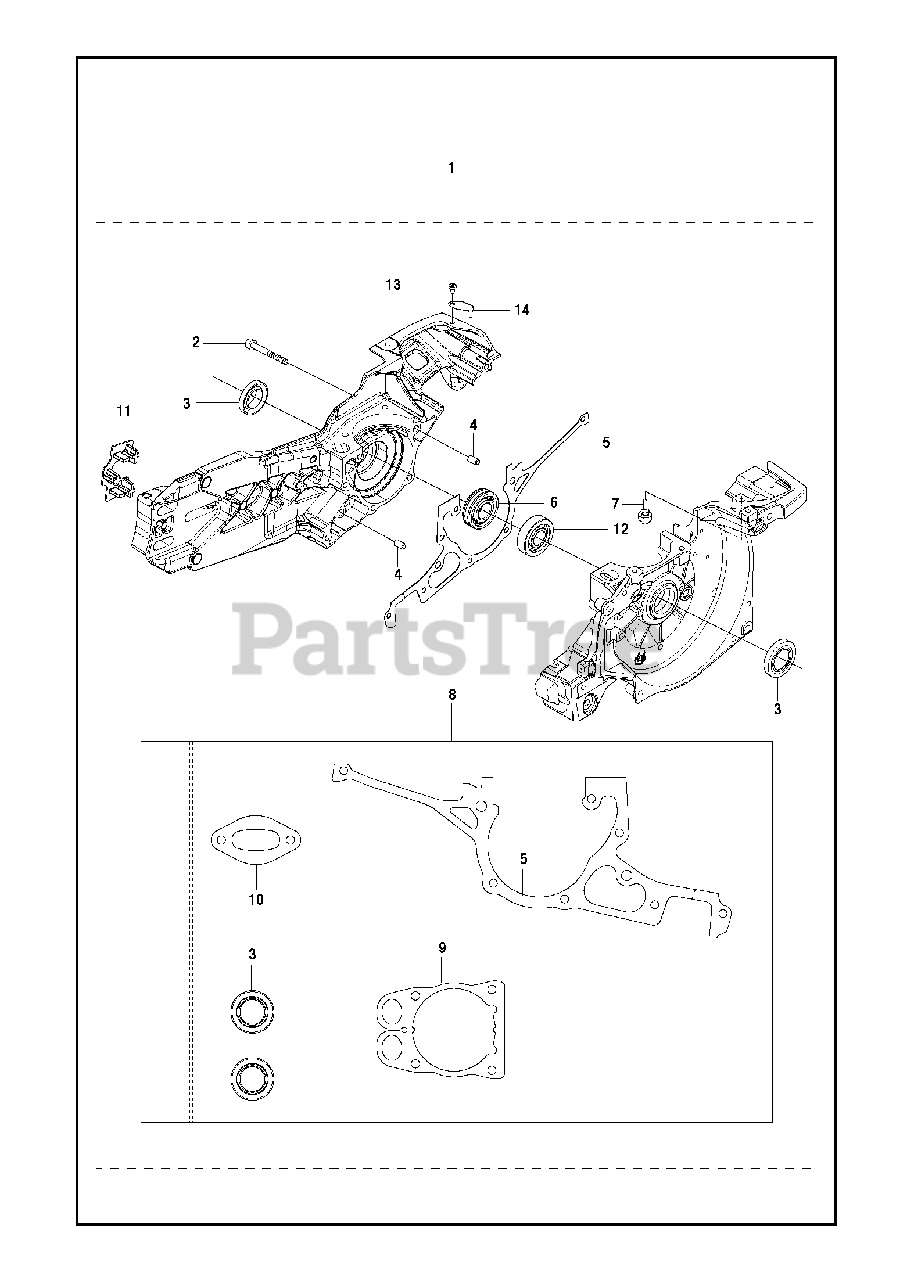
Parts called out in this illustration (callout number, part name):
2	SCREW ITXSCM
3	SEALING RING
4	GUIDE BUSHING
7	RUBBER BUSHING
12	BALL BEARING
